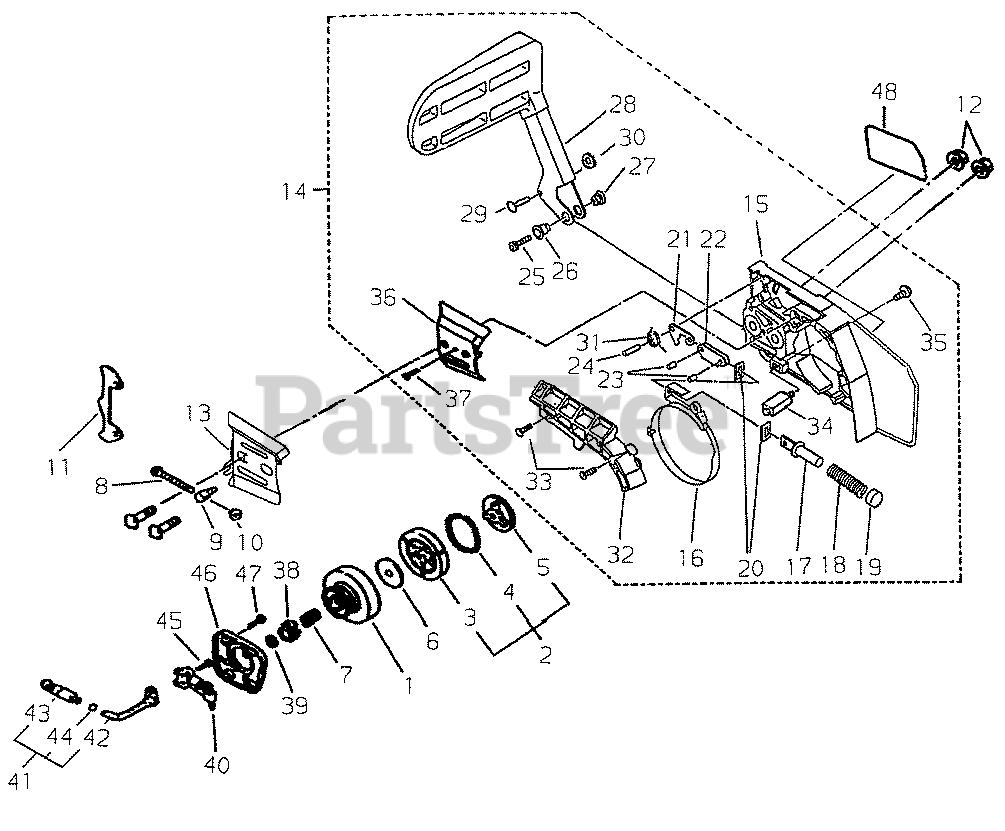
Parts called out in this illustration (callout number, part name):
2	CLUTCH ASSY
3	SHOE, CLUTCH
4	SPRING, CLUTCH
5	HUB, CLUTCH - OUTER
6	HUB, CLUTCH - INNER
7	BEARING, NEEDLE
8	SCREW
9	TENSIONER, CHAIN
10	PUSHNUT
11	SPIKE
12	NUT, GUIDE BAR
13	PLATE, GUIDE
14	CLUTCH COVER ASSY
15	COVER, CLUTCH
16	BAND, BRAKE
17	HOLDER, SPRING
18	SPRING, BRAKE
19	STOPPER
20	ADJUST PLATE
21	LEVER - INNER
22	TIE, CABLE
23	PIN - LOCATING
24	PIN - LOCATING
25	SCREW - 4X12
27	NUT
28	LEVER
30	NUT
31	SPRING, LEVER
32	COVER
33	SCREW - 4X12 -- TAPPING
34	CATCHER, CHAIN
35	SCREW - 3X10
36	GUIDE PLATE B
37	SCREW - 4X8 -- TAPPING
38	GEAR
39	PLATE, THRUST
40	AUTO-OILER ASSY
41	OIL FILTER ASSY
42	PIPE - OIL
43	FILTER, OIL
44	CLIP, OIL
45	SCREW - 4X12
46	COVER, PUMP
47	SCREW - 4X12
48	LABEL - TRADE
